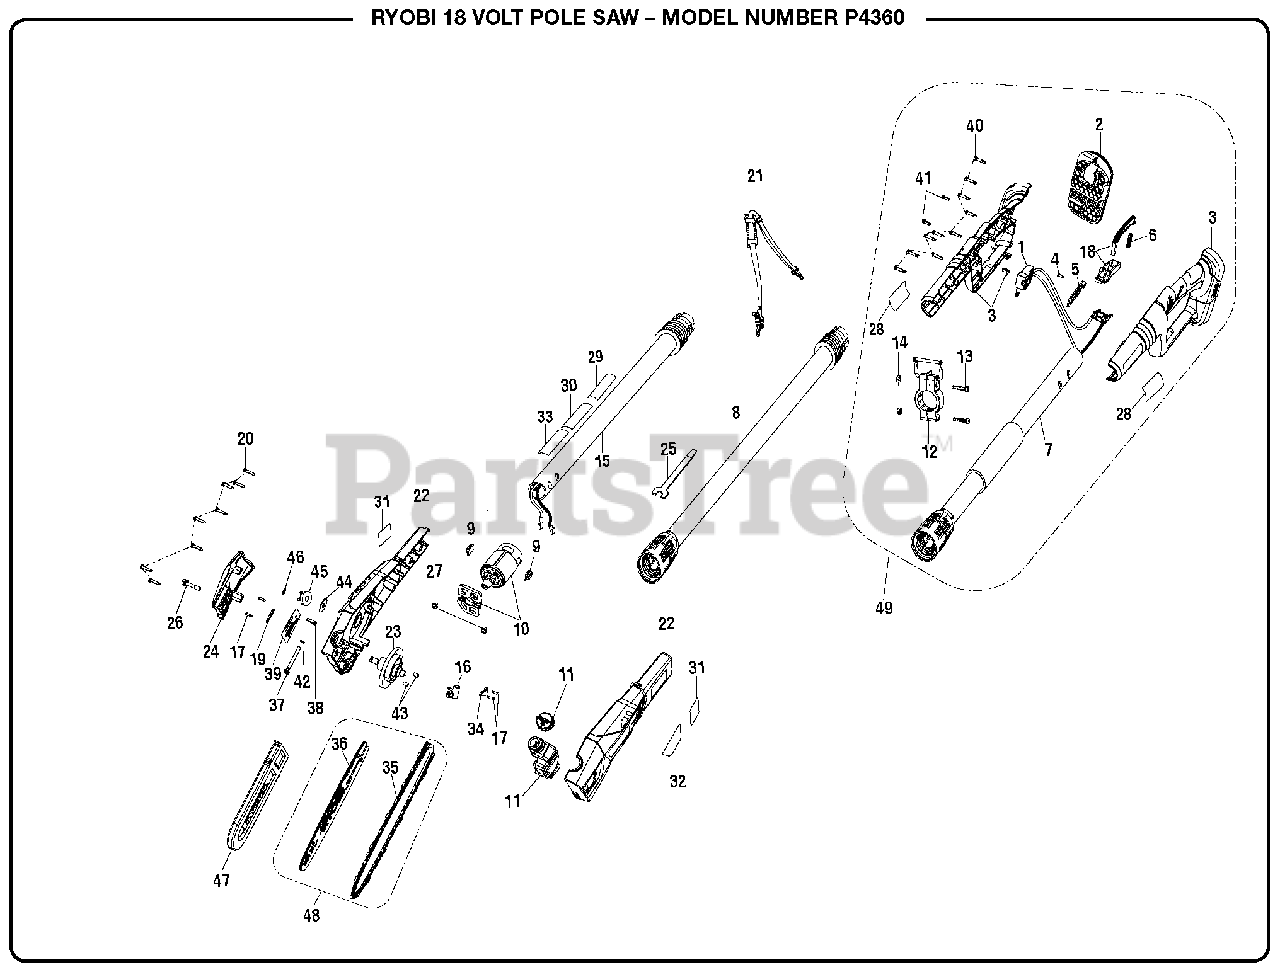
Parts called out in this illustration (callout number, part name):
1	Switch Assembly
2	18v Battery Foot
3	Handle Assembly
4	Screw (M3 x 8 mm)
5	Strap Hanger
6	Compression Spring
7	Lower Pole Assembly
8	Middle Pole Assembly
9	Rubber Pad
10	Motor Assembly
11	Oil Tank And Cap Assembly
12	Clamp Assembly
13	Screw (M5 x 24 mm, Pan Hd.)
14	Hex Nut (M5)
15	Top Pole Assembly
16	Oil Pump
17	Screw (M3 x 10 mm)
18	Rear Trigger & Lock Button Assembly
19	Seal Gasket
20	Screw (M4 x 18 mm T15 Torx Hd.)
21	Harness Assembly
22	Housing Assembly
23	Output Shaft Assembly
24	Chain Cover
26	Bolt w/Washer (M6 x 29 mm, Hex Soc. Hd.)
27	Screw w/Washer (M4 x 8 mm)
28	Logo Label
29	Warning Label (English)
30	Warning Label (French/Spanish)
31	Logo Label
32	Data Label
33	Warning Icon Label
34	Pump Clamp
36	Guide Bar
37	Adjustment Bolt (M5 x 46.5 mm)
38	Adjustment Guide Bar
39	Guide Bar Plate
40	Screw (M4 x 18 mm, T20 Torx Pan Hd.)
41	Screw (M4 x 11 mm, T20 Torx Pan Hd.)
42	Retaining Ring (4 mm)
43	Contact Plate Stopper
44	"D" Washer (OD25 x ID7.5 x 1t)
46	Retaining Ring
48	Bar & Chain Assembly
49	Rear Handle Assembly
